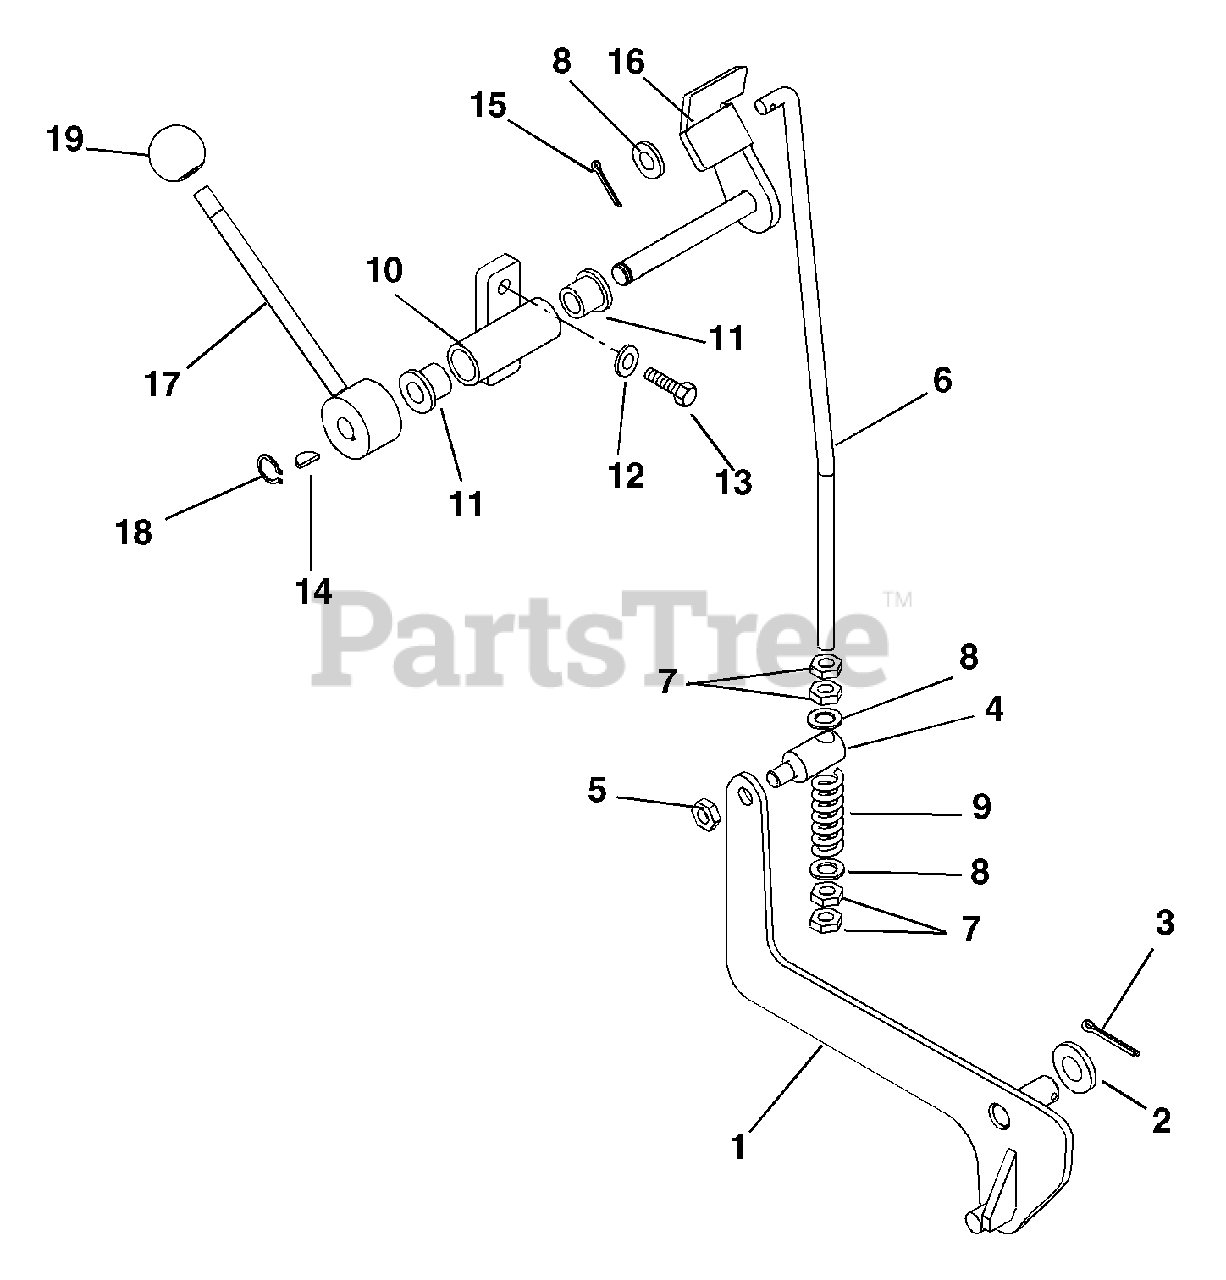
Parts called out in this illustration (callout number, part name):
1	Weldment, Parking Brake Arm
2	Washer, Flat-Steel .63 x 1.25 x .062
3	Pin, Cotter .12 x 1.50
4	Trunnion
5	Nut, Locking-Nylon M10-1.5
6	Linkage, Brake
7	Nut, Jam M10-1.5
8	Washer, Flat-Steel .406 x .812 x .065
9	Spring, Compression .143 x .71 x 2.00
10	Weldment, Actuator Pivot
11	Bushing, Flange .50 x .75 x .75 x 1.00
12	Washer, Locking .31 x .078 Regular
13	Bolt, Hex M8 x 1.25 x 30 Grade 5
14	Key, Woodruff .13 x .63
15	Pin, Cotter .09 x 1.00
16	Weldment, Actuator
17	Weldment, Brake Lever
18	Ring, Retaining-External .50 x .035
19	Knob, Steering Lock
